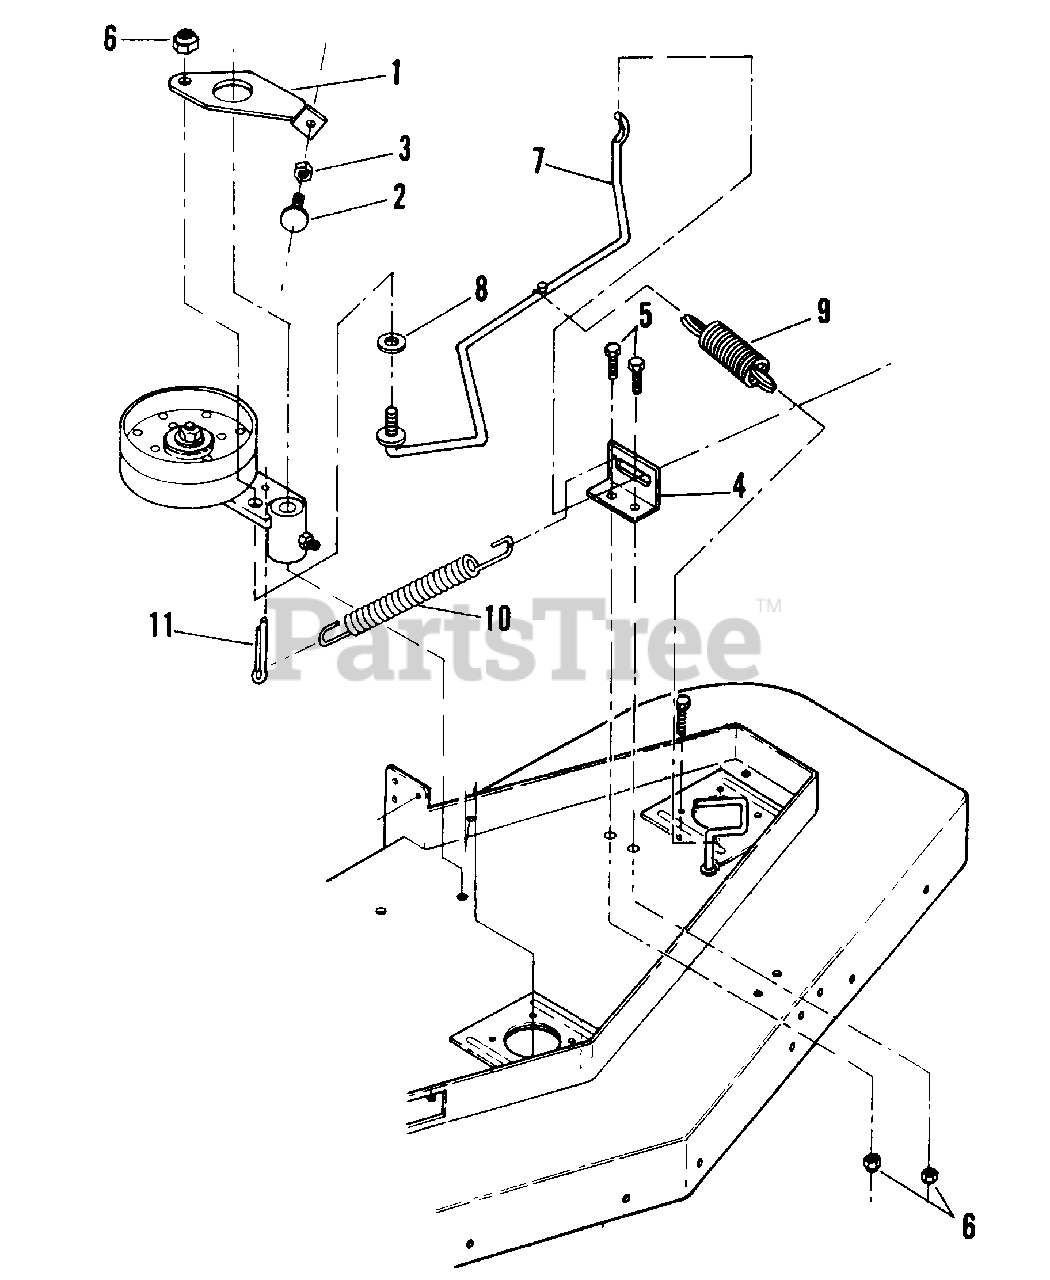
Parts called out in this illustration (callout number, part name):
1	ARM, Brake 48"
2	BOLT, 5/16C x 1-11/4" Grade 2 Carriage
3	NUT, 5/16C Hex Jam
4	BRACKET, Brake
5	SCREW, 3/8C x 3/4" Grade 5 Hex Cap
6	NUT, 3/8C Nyloc
7	BELT GUIDE, Brake
8	WASHER, 3/8" Wave
9	SPRING, Traction
10	SPRING, Idler Return
11	PIN, 3/16 x 3/4"
